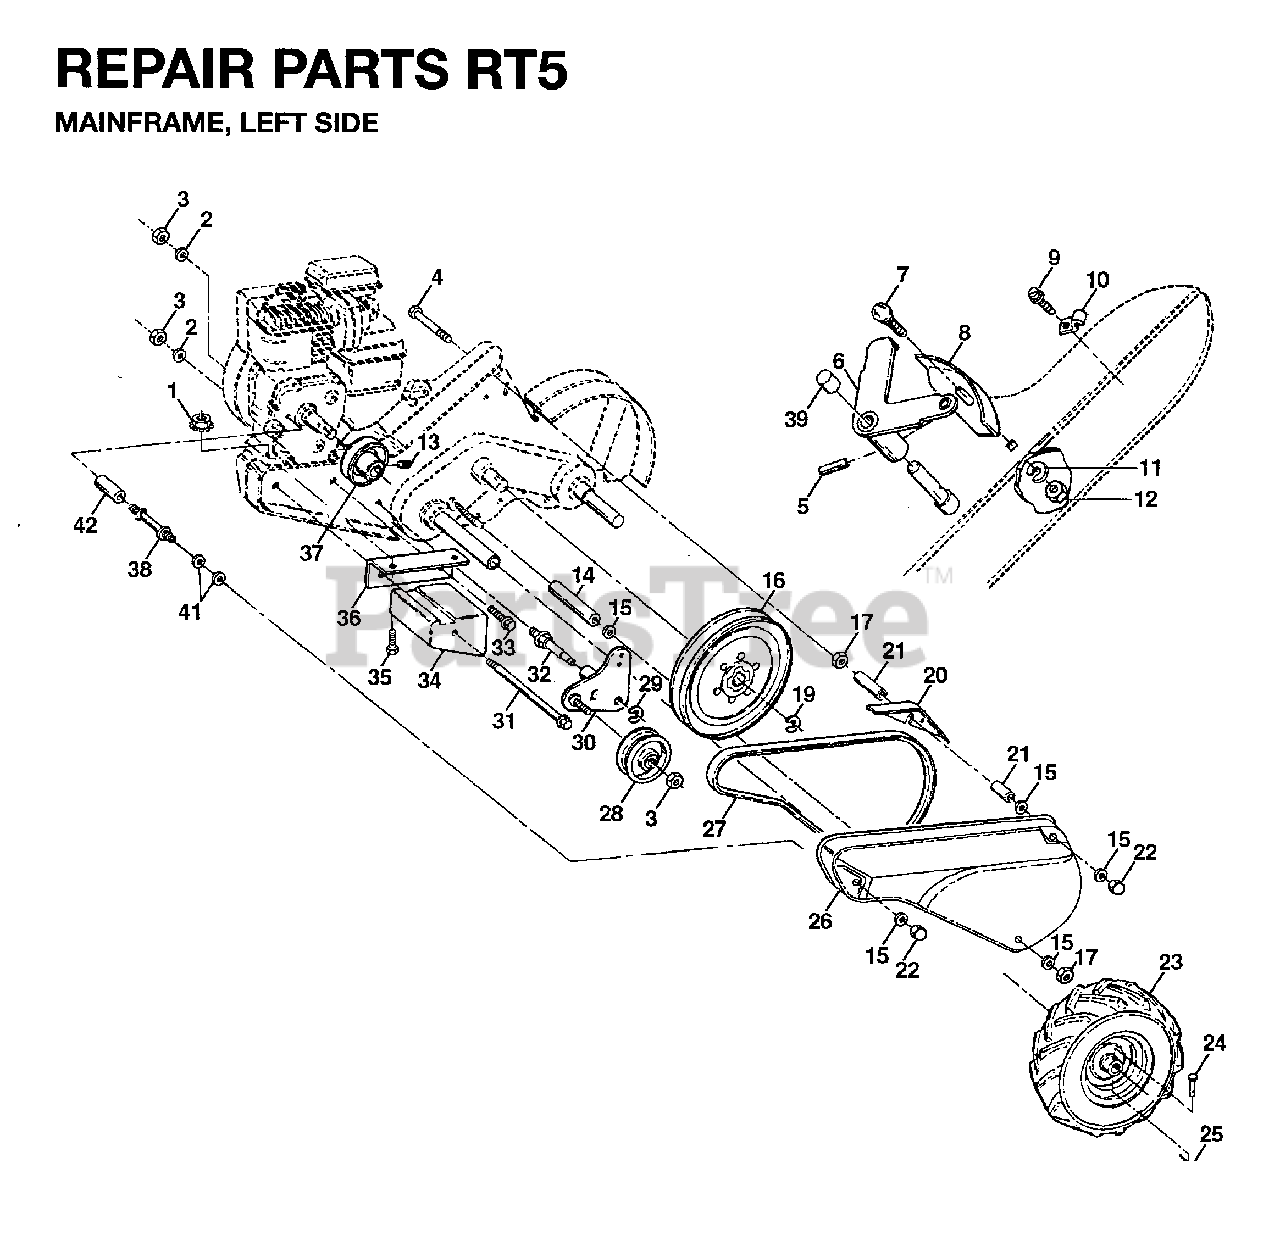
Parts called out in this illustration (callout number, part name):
1	LOCKNUT
2	WASHER, LOCK 3/8
3	NUT.HEX.3/8-16UNC
5	DRIVE PIN
6	LIFT LEVER
10	CONDUIT CLIP T
11	LOCKWASHER
12	NUT
13	SET SCREW **
14	SPACER
15	WASHER - 15X7.3X1.6
16	SHEAVE, TRANSMISSION
19	RETAINING RING
20	GUARD CRT
21	SPACER, SPLIT
24	RIVET,DRILLED
25	RETAINER M
27	V-BELT
28	PULLEY-IDLER TI
29	KLIP RING
30	BRACKET ASSY TI
31	BOLT.FIN.HEX.3/8-16UNC
32	SHIFT ARM CRT
34	COUNTERWEIGHT.LH.CRT
36	BRACKET LH CRT
37	ENGINE PULLEY
38	BELT GUARD STUD
39	CAP.PLUNGER.BLACK
5320651-39	VALVE STEM LT
5321289-52	WHEEL.8X2-3/4.TILLER /RIM ONLY
